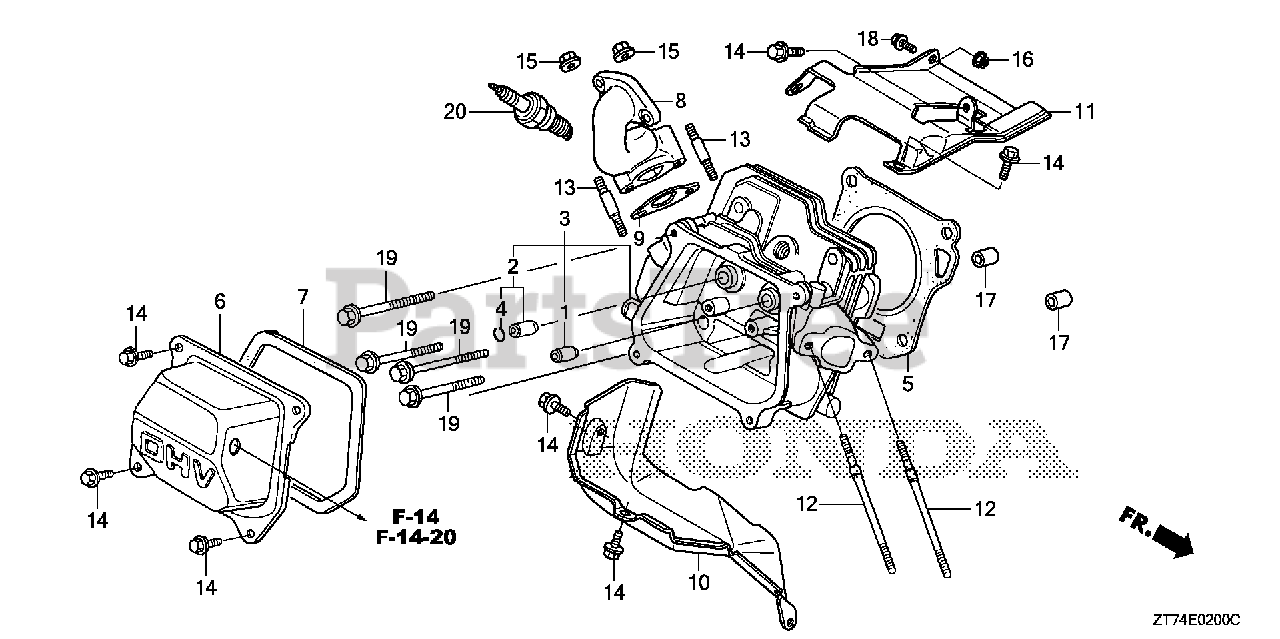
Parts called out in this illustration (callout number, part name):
1	GUIDE, VALVE (OVER SIZE)
2	GUIDE, EX. VALVE (OVER SIZE)
3	CYLINDER HEAD
4	CLIP, VALVE GUIDE
5	GASKET, CYLINDER HEAD (NIPPON LEAKLESS)
6	COVER, HEAD
7	GASKET, HEAD COVER
9	GASKET, MUFFLER
11	SHROUD (UPPER)
12	BOLT, STUD (6X115) (CT200)
13	BOLT, STUD (8X65) (CT200)
14	BOLT, FLANGE (6X12) (CT200)
15	NUT, FLANGE (8MM)
16	NUT, FLANGE (6MM)
17	PIN, DOWEL (10X16)
18	BOLT, FLANGE (6X18)
19	BOLT, FLANGE (8X60)
20	SPARK PLUG (BPR5ES) (NGK)
20	SPARK PLUG (W16EPR-U) (DENSO)
20	SPARK PLUG (BPR6ES) (NGK)
20	SPARK PLUG (W20EPR-U) (DENSO)
